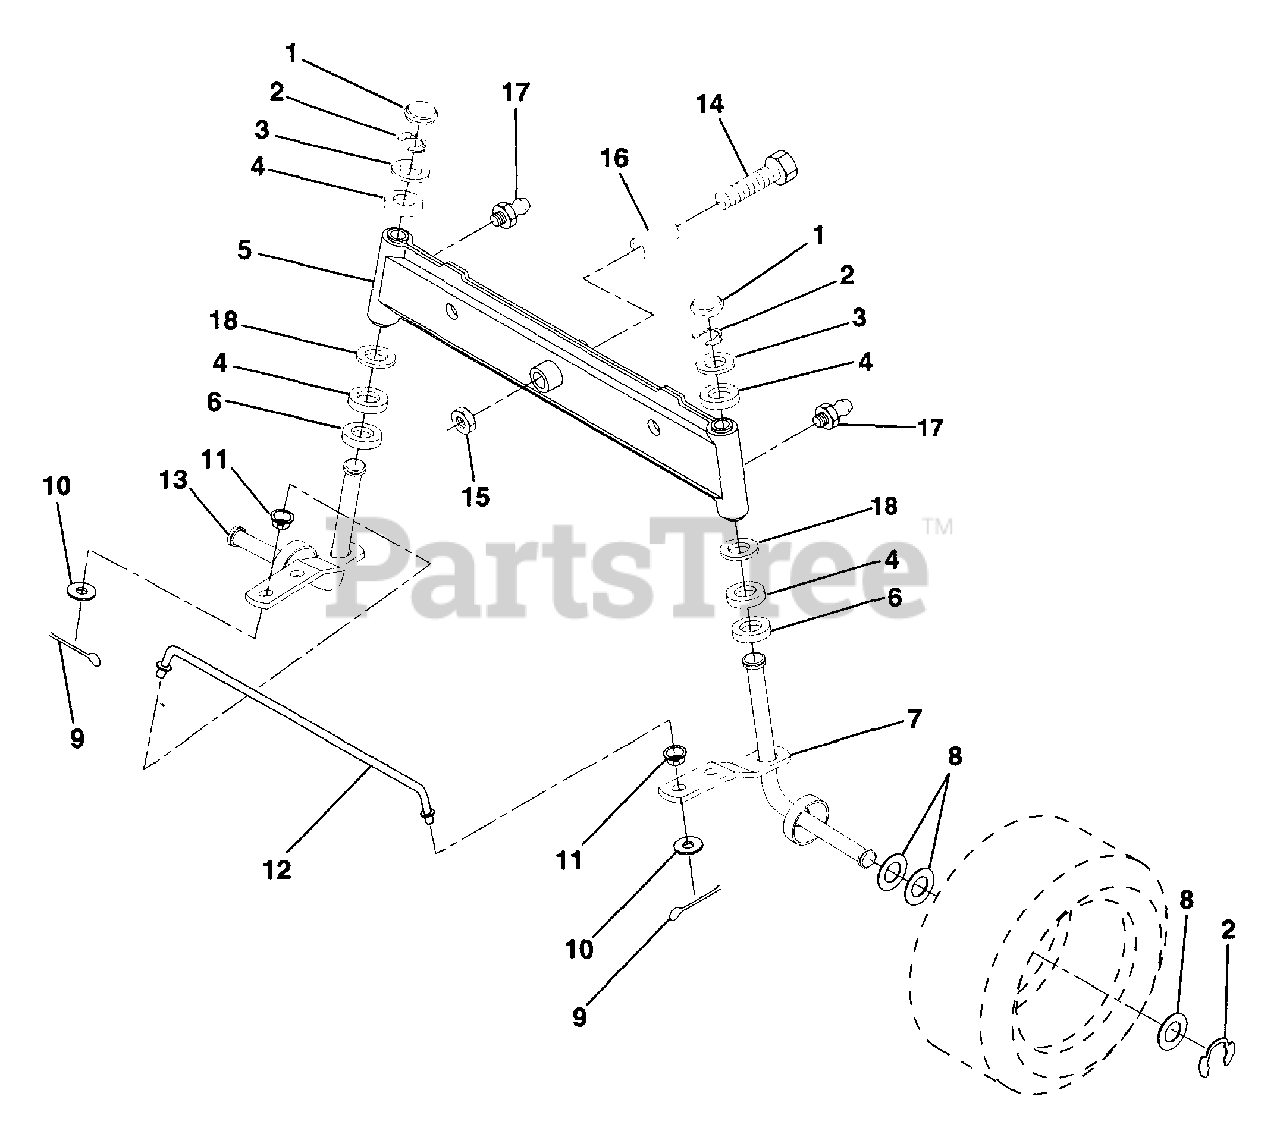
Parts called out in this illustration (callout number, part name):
1	Cap, Spindle
2	Ring, Clip
3	Washer 25/32 x 1-5/8 x 16 Gauge
4	Bearing
5	Axle, Front
6	Bearing, Thrust
7	Spindle Assembly, R.H.
8	Washer 25/32 x 1-1/4 x 16 Gauge
9	Pin, Cotter 1/8 x 3/4
10	Washer 13/32 x 13/16 x 16 Gauge
12	Tie Rod
13	Spindle Assembly, L.H.
14	Bolt Hex 5/8-11 Unc x 3-1/2
15	Nut Lock Flange 5/8-11 Unc
16	Spacer Bearing
17	Fitting Grease
18	Washer 27/32 x 1-1/4 x 16 Ga.
